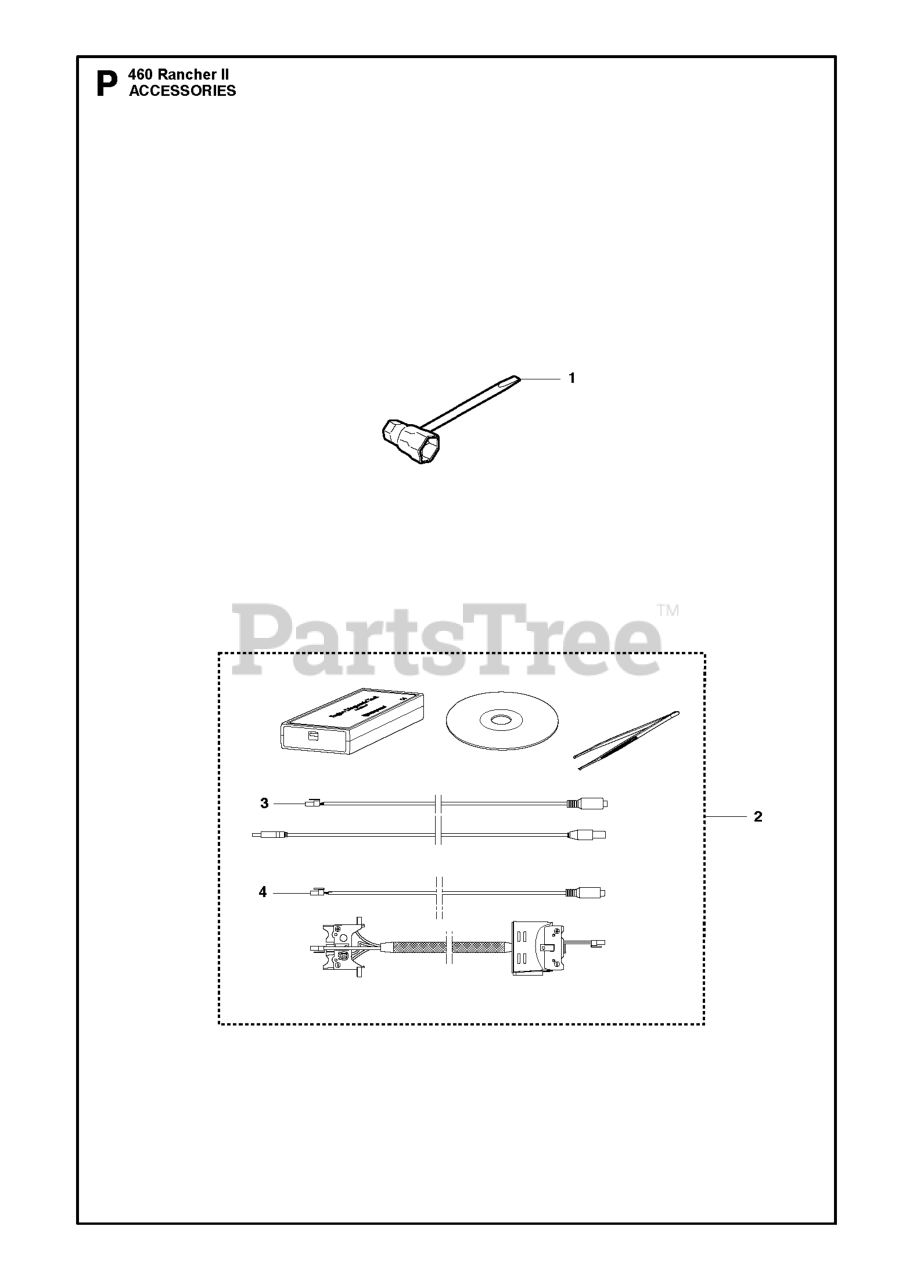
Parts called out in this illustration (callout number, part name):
1	COMBI TOOL
2	DIAGNOSTIC TOOL KIT
3	CABLE ASSY
4	CABLE ASSY
